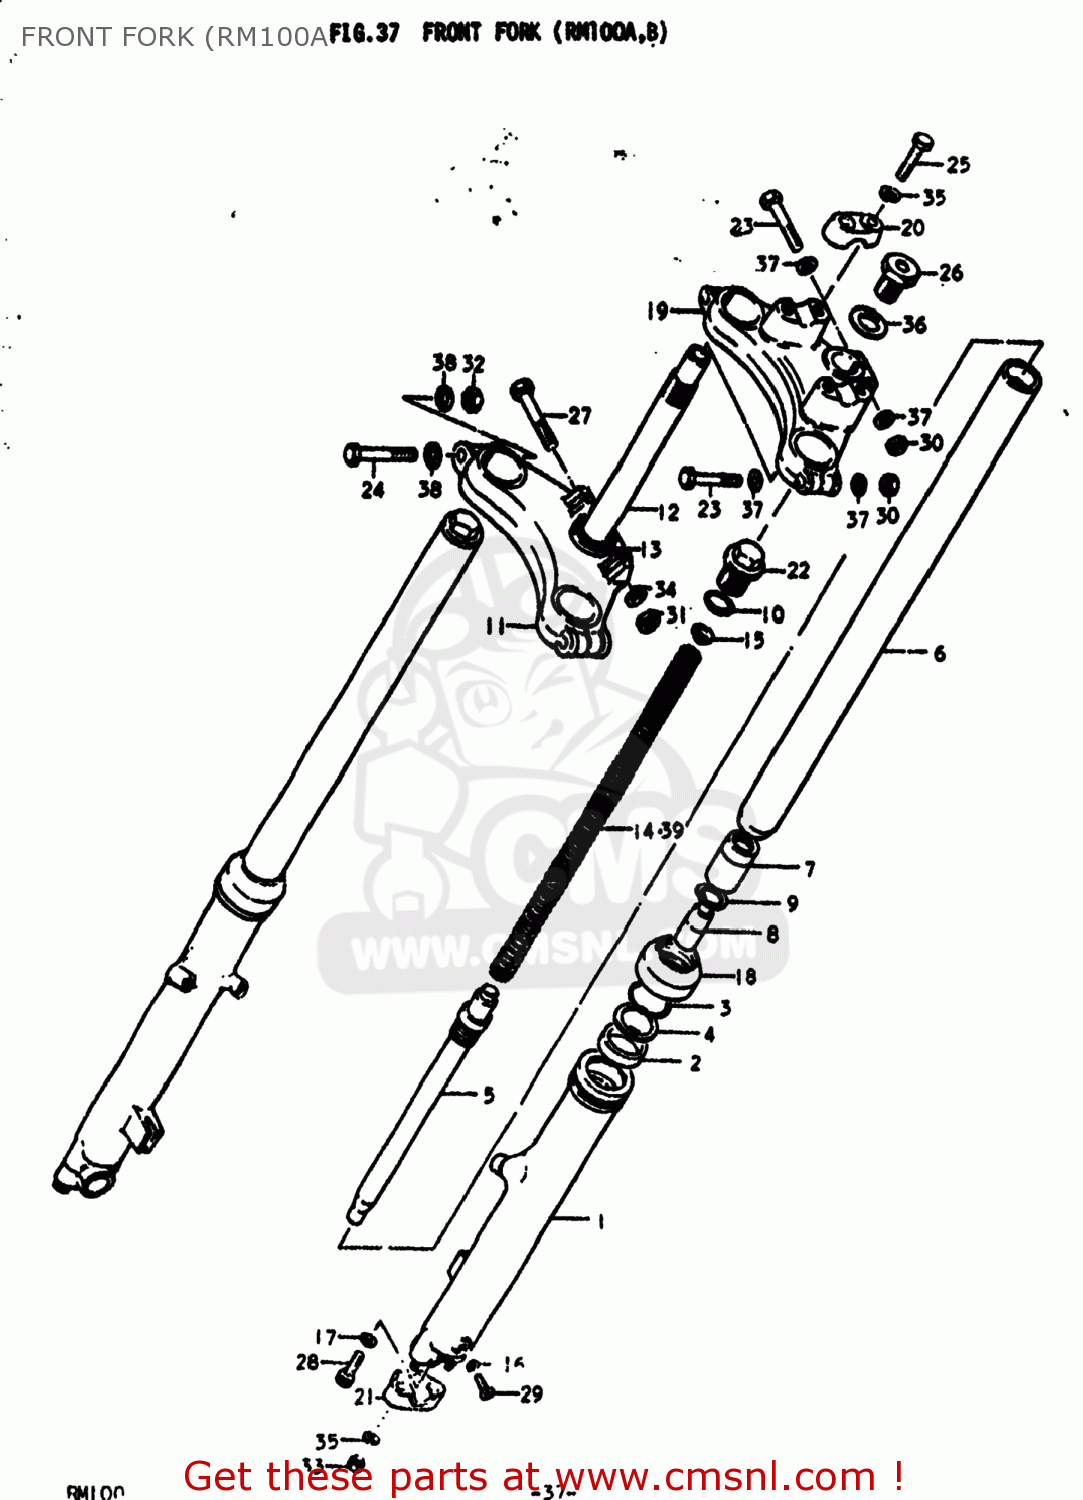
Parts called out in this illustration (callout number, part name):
0	DAMPER SET
1	TUBE,OUTER,LEFT
2	SEAL,OIL
3	RING,SNAP
4	WASHER,FRONT FORK
5	CYLINDER,FRONT FORK
6	TUBE,FORK,INNER
7	PISTON
8	PIECE,OIL LOCK
9	SNAP RING
10	O-RING,FORK INNER TUBE
11	STEM,STEERING
12	STEM,STEERING
13	RACE,STEERING OUTER LWR
14	SPRING
15	GUIDE,SPRING
16	GASKET,DRAIN,PLUG (NAS)
17	GASKET
18	SEAL,DUST
19	HEAD,STEERING STEM
20	HOLDER,HANDLEBAR
21	HOLDER,AXLE
22	BOLT,FR FORK
23	Bolt 8X50
24	BOLT
25	Bolt
26	CAP
27	BOLT
28	BOLT
29	SCREW
30	NUT
31	NUT
32	NUT
33	NUT (8MM)
34	LOCK WASHER
35	LOCK WASHER
36	WASHER,STEM HEAD
37	WASHER
38	WASHER
39	SPRING
